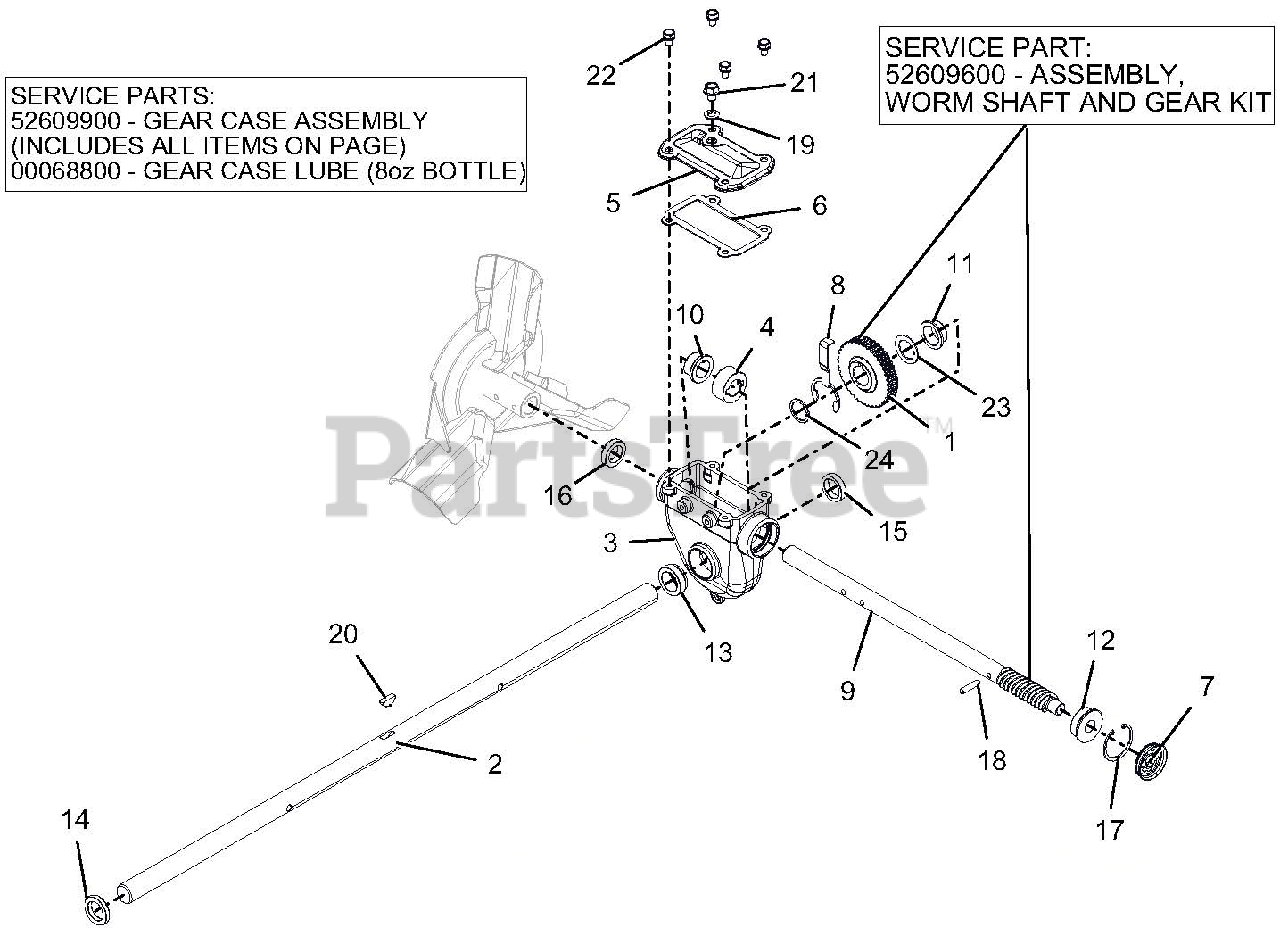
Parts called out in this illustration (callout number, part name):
1	WORM GEAR
2	SHAFT, RAKE-36"
3	GEARCASE, LARGE MACHINED
4	THRUST COLLAR, .875"ID SLIPFIT
5	COVER, TOP - LARGE IRON
6	GASKET, TOP - LARGE GEARCASE
7	COVER, GEAR CASE 1.75"
8	BUSHING RETAINER, LARGE
9	SHAFT, WORM - PRO
10	BSHG-FLG .879X1.128X.75X1.45
11	BSHG-FLG 1.006X1.128X.555X1.45
12	BSHG-FLG .628X1.503X.58X1.725
13	BSHG-FLG LARGE, RIGHT
14	SEAL-OIL .999X1.500X.250 TBC29
15	SEAL-OIL .999X1.375X.312 TBC29
16	SEAL-OIL .873X1.375X.312 TBC29
17	RG-RTNG-INT 1.750X.062
18	PIN-STR .250X1.12 6150
19	WSHR-BND-SEAL .38X.75X.11 GALV
20	KEY-WDRF .25X.875 HRD #A
21	@SCR-ROLOK .38-16X.50 HWH YWZC
22	BOLT, SEMS .31-18X.50 GR5 YWZC
23	WSHR-FL-STL 1.010X1.505X.062YZ
24	WSHR-FL-STL 1.010X1.250X.068YZ
25	GEAR CASE, 36" IRON PRO TOP-LD
26	ARIENS L3 LUBE, 8 OZ BOTTLE
